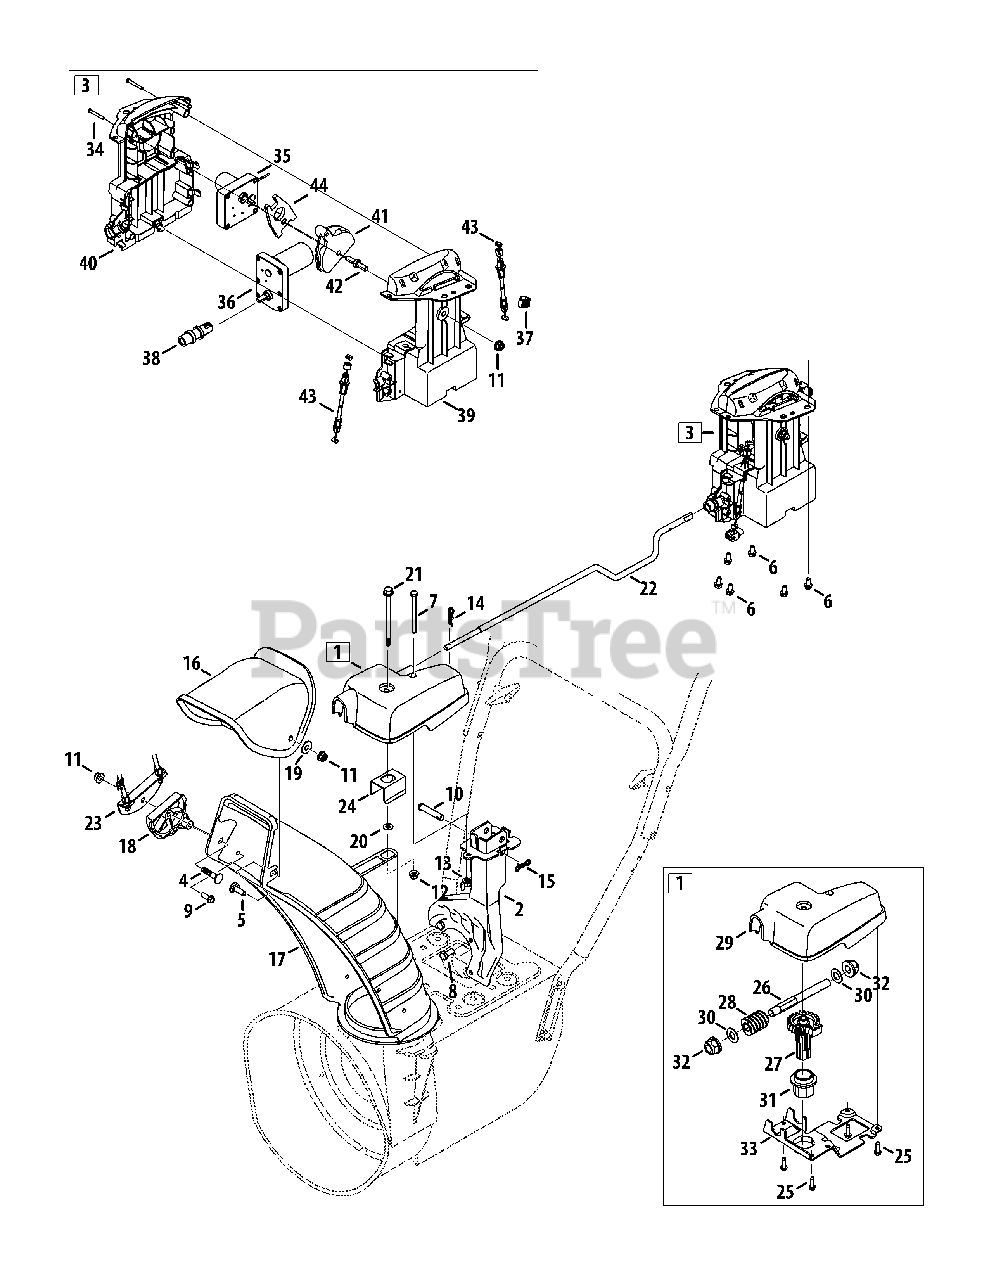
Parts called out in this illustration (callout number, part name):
1	Gearbox Assembly, Chute Rotation
2	Chute Support Bracket
3	Chute Assembly, 4-Way Elec.
4	Bolt, Carriage, 5/16-18 x 1.50
5	Bolt, Carrier, 5/16-18 x 1.00
6	Screw, HL, 1/4-15 x 0.50
7	Hex Head Screw, 1/4-20 x 3.00
8	Hex Head Screw, 5/16-24 x .750
9	Screw, HL, 1/4-15 x 0.750
10	Clevis Pin, 3/8 x 1.87
11	Nut, Flangelock, 5/16-18
12	Nut, Flangelock, 1/4-20
13	Wing Nut, 1/4-20
14	Internal Cotter Pin
15	Bow-Tie Cotter Pin
16	Chute, Upper
17	Chute, Lower
18	Cable Guide, Chute Tilt
19	Washer, Flat, .349 x .879
20	Washer, Flat, .25 x .630
21	Screw, Shoulder, .312 x 3.5 x 1/4-20
22	Chute Crank Rod
23	Cable Bracket
24	Chute Bracket
25	Screw, 12-16 x .75
27	Gear, 23 T
30	Flat Washer, .510 x 1.00 x .060
31	Flange Bearing, 1.00 ID
32	Flange Bearing, .50 ID
33	Gear Bracket
34	Screw, #10-16 x 1.25
35	Chute Pitch Motor
36	Chute Rotation Motor
37	Cable Clip
38	Electric Chute Coupler
39	Housing, LH
40	Housing, RH
41	Cable Guide
42	Hex Screw, 5/16-18 x .75
43	4-Way Cable
43	4-Way Cable w/Clip
44	Chute Pitch Adapter
